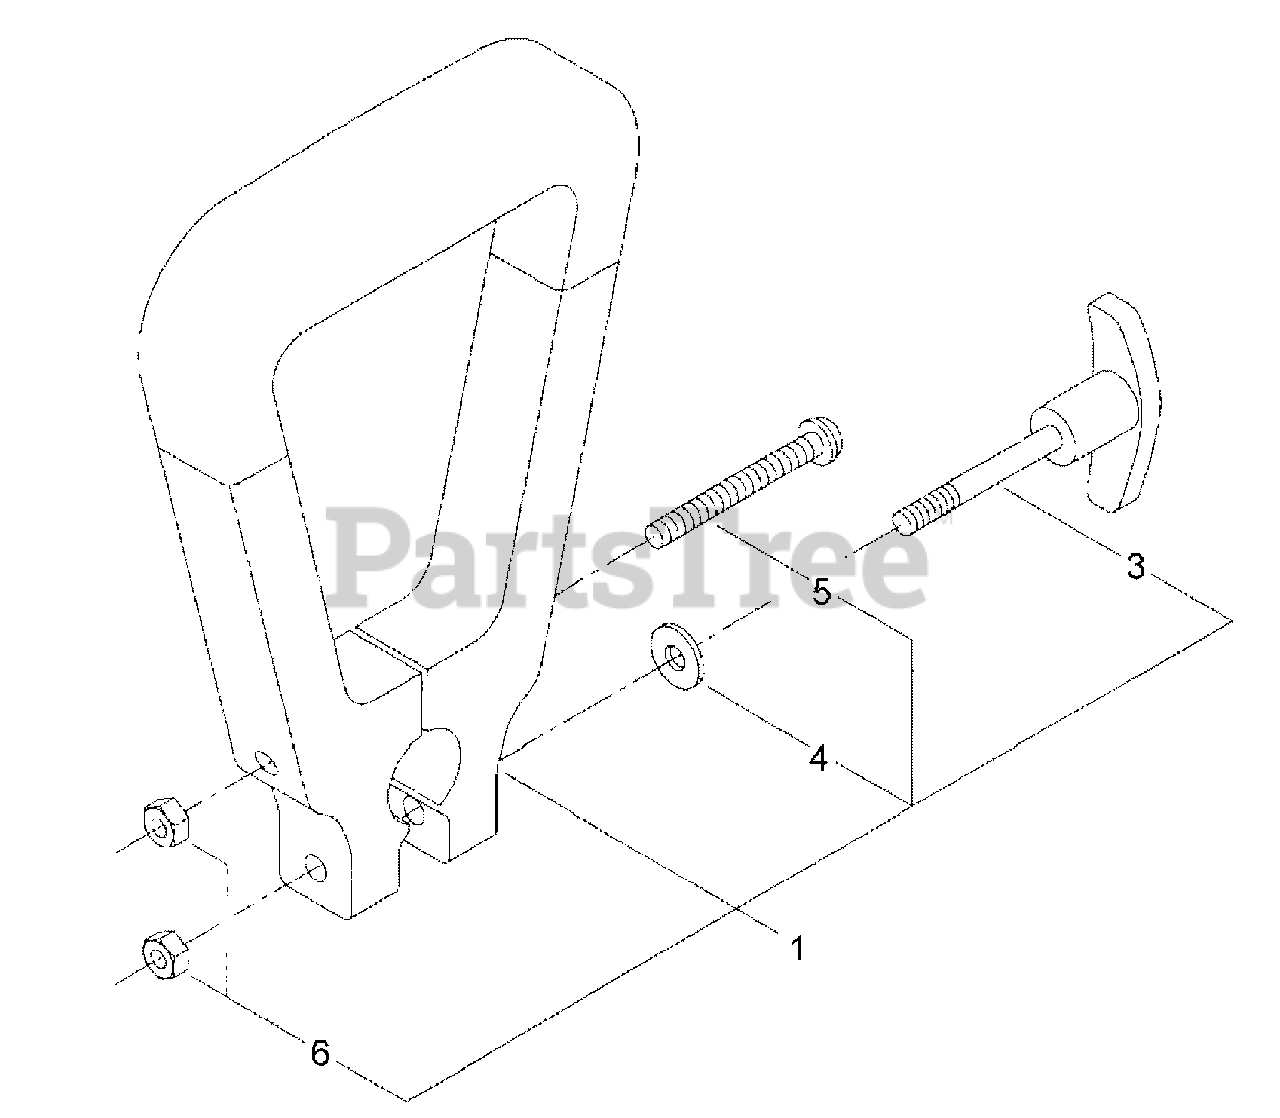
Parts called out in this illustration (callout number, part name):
1	HANDLE ASSY
3	THUMBSCREW
4	WASHER
5	SCREW
6	NUT - 6
